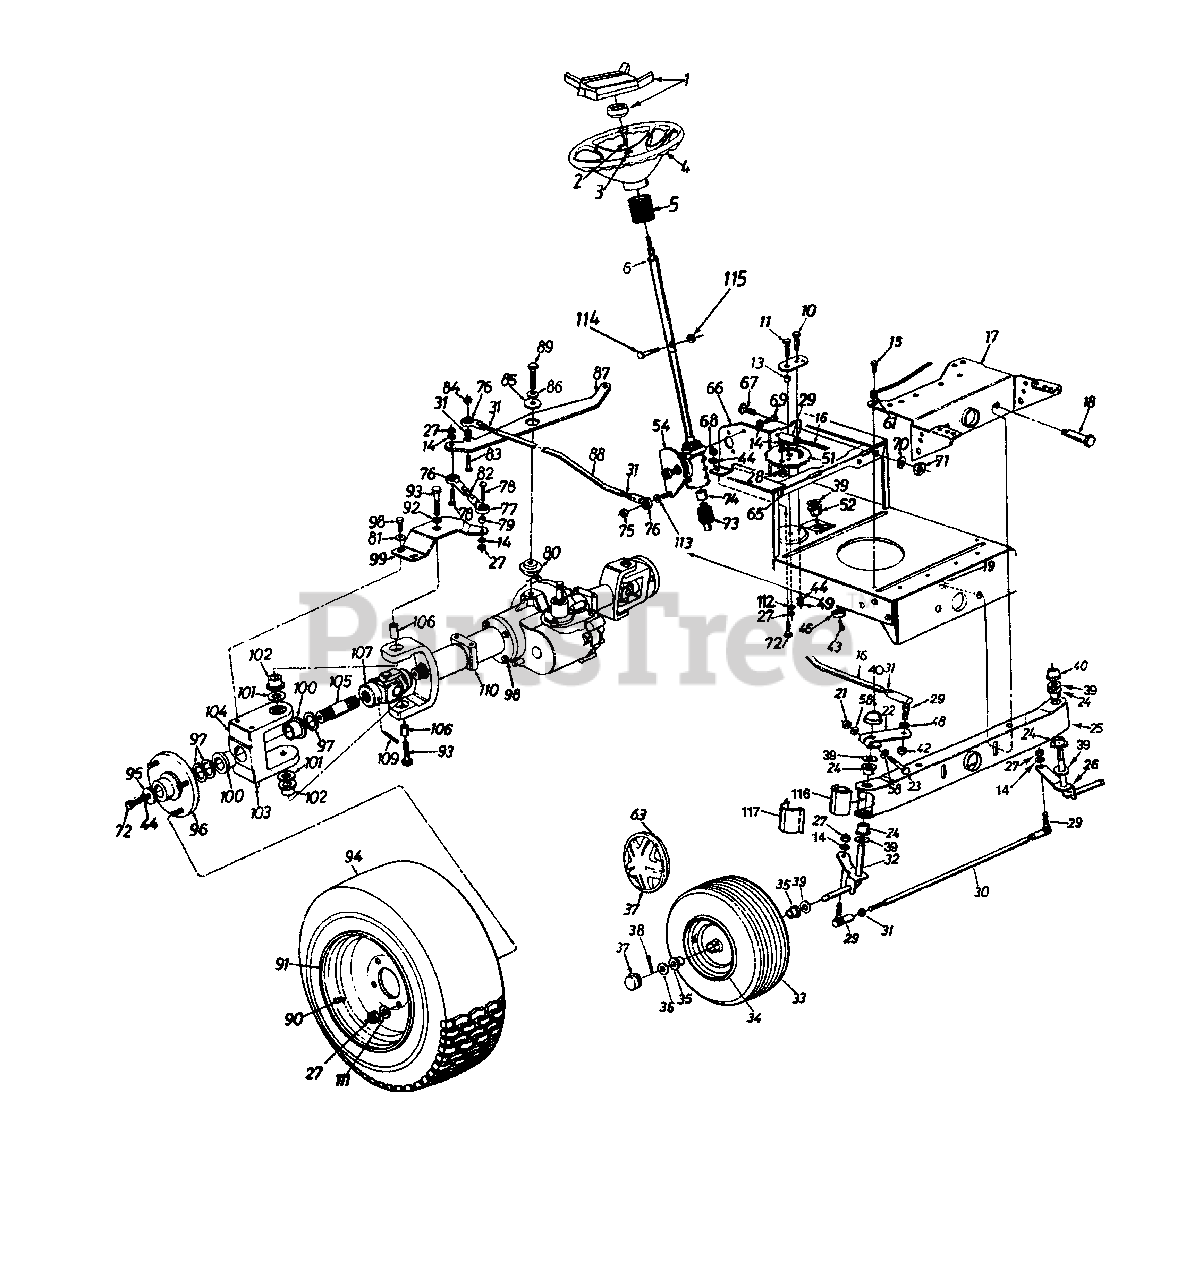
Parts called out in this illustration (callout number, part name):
1	Steering Wheel Insert
2	Hex Patch Bolt 5/16-18 x 1" Lg.
3	Belleville Wash. .345" I.D.
4	Steering Wheel (4 Spoke)
5	Steering Bellow
6	Upper Steering Shaft
10	Shoulder Bolt .437" Dia. x .35" Lg.
11	Hex Bolt 3/8-24 x 1.0" Lg.(Grade 5)
13	Spacer .380" I.D. x .625" O.D. x .227"
14	L-Wash. 3/8" I.D.
15	Hex Wash. Hd. Self-Tap Scr.
16	Steering Drag Link
18	Shoulder Bolt .498" Dia. x 2.04" Lg.
19	Hex L-Nut 3/8-16 Thd.
21	Hex Cent. L-Nut 5/16-24 Thd.
22	Steering Arm Front Axle
23	Hex Bolt 5/16-24 x 2.00" Lg. (Grade 5)
24	Hex Flg. Brg. .634" I.D.
26	Front Axle Ass'y.-L.H.
27	Hex Nut 3/8-24 Thd.
28	Hex Jam Nut 3/8-24 Thd.
29	Ball Joint 3/8-24 Thd.
30	Tie Rod
31	Hex Jam Nut 3/8-24 Thd.
32	Front Axle Ass'y.-R.H.
33	Wheel Ass'y. Comp.
34	Front Wheel Rim Only
35	Bearing
36	Fl-Wash. .635" I.D. x 1.59" O.D.
37	Front Hub Cap
38	Cotter Pin 1/8" Dia. x 1.25" Lg.
39	Fl-Wash. .640" I.D. x .24" O.D.
40	Push Cap
43	Pan Hd. Bolt 5/16-18 x .62"
44	L-Wash. 5/16" I.D.
46	Cap
48	L-Wash. 3/8" I.D.
49	Hex Nut 5/16-18 Thd.
51	Steering Gear Segment
52	Hex Flg. Brg. .634 I.D.
54	Steering Box Ass'y. Comp.
58	Wave Wash. .32" I.D. x .62"
61	Ext. L-Wash. 5/16" I.D.
63	Spring Clip
65	Horizontal Cross Bracket
66	Vertical Mounting Bracket
67	Hex Bolt 1/4-28 x .75" Lg.
68	Hex Nut 5/16-24 Thd.
69	Hex Bolt 3/8-16 x 1.0" Lg.
70	Bell-Wash. .265" I.D. x .75"
71	Hex Nut 1/4-28 Thd.
72	Hex Bolt 5/16-24 x .75" Lg.
73	Pinion Shaft
74	Steering Shaft Splined Coupler
75	Hex L-Nut 3/8-24 Thd.
76	Rod End 3/8-24 Thd.-R.H.
77	Rod End 3/8-24 Thd.-L.H.
78	Hex Bolt 3/8-24 x 1.5" Lg.(Gr. 5)
79	Spacer .38" I.D. x .625"
80	Shld. Spacer .51" I.D.
81	Bell-Wash. .38" I.D. x .88"
82	Tie Rod
83	Hex Bolt 3/8-24 x 1.25" Lg.
84	Hex Patch L-Nut 3/8-24 Thd.
85	Fl-Wash. .531" I.D. x 1.75"
86	Bell-Wash. .505" I.D. x 1.0"
89	Hex Bolt 1/2-13 x 1.5" Lg. (Gr. 5)
90	Air Valve
93	Hex Bolt 1/2-20 x 1.75" Lg.(Gr. 5)
95	Fl-Wash. .33" I.D. x 1.25"
96	Wheel Flange Ass'y.
97	Fl-Wash. 1.0" x 1.56"
98	Hex Bolt 3/8-24 x 1.25" Lg.
101	Fl-Wash. .76" I.D. x 1.5"
102	Flange Brg. 3/4" I.D.
103	Grease Fitting
104	Wheel Brg. Housing
105	Wheel Flange Ass'y
106	Pivot Sleeve
107	U-Joint
109	Grooved Roll Pin 1.0" Lg.
110	Axle Horn Ass'y.
111	Bell-Wash. .38" I.D. x .88"
112	Bell-Wash. .39" I.D. x 1.38"
113	Fl-Wash. .385" I.D. x .62"
114	Hex Bolt 1/4-20 x 1.31" Lg.
115	Hex Ins. L-Nut 1/4-20 Thd.
116	Pivot Bar End Cap
117	Axle Cap
